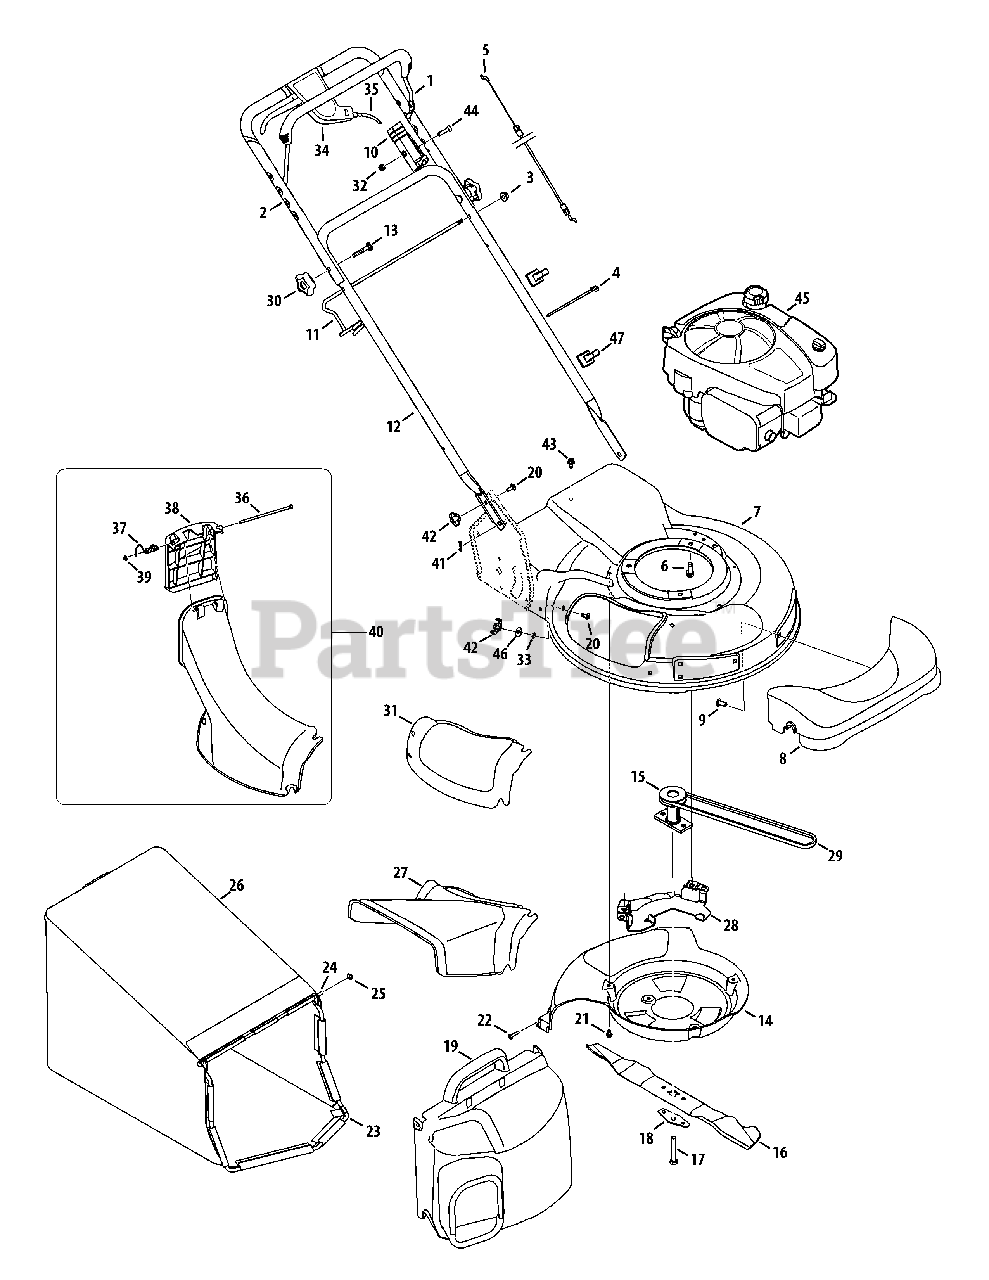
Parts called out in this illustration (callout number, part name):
1	Blade Control
2	Upper Handle
3	Flange Lock Nut, 5/16-18
4	Cable Tie
5	Control Cable
6	TT Screw, 3/8-16 x 1.00
7	21-inch Deck
8	Front Axle Cover
9	HL Screw, 5/16-14 x .750
10	Housing
11	Grass Bag Support Rod
13	Carriage Bolt 5/16-18 x 2
14	Rear Baffle
15	Blade Adapter
16	21-inch Mulching Blade
17	HH Cap Screw, 3/8-24 x 2.50
18	Bell Blade Spacer
19	Grass Bag Cover Assembly
20	Carriage Screw 1/4-20 x .75
21	TT Screw 1/4-20 x .375
22	HL Screw 1/4-15 x .75
23	Grass Bag Frame
24	Grass Bag Pivot Rod
25	Cap Speed Nut
26	Grass Bag Assembly
27	Side Discharge Chute
28	Belt Keeper
29	V-Belt
30	Star Knob
31	Mulch Cover
32	Hexlk Nut, 1/4-20
33	Push Nut
34	Drive Control Assembly
35	Drive Cable
36	Chute Door Pivot Rod
37	Torsion Spring
38	Top Discharge Door Chute
39	Push Cap
40	Top Discharge Chute Assembly
41	Cotter Pin
42	Wing Nut
43	TT Screw, 5/16-18 x .500
44	Screw, 1/4-20 x 1.310
46	Flat Washer, .260 x .720 x .060
47	Cable Guide
